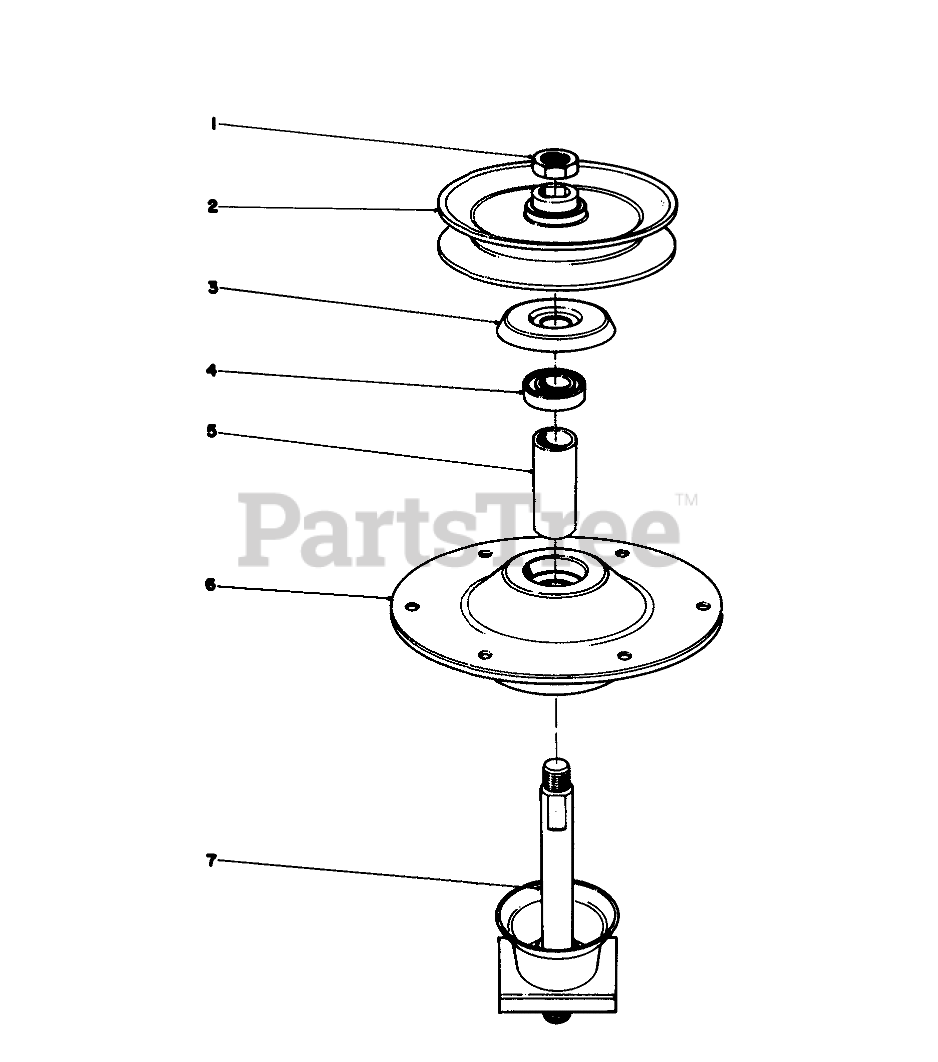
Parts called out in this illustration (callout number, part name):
1	Locknut
2	PULLEY B
3	COVER-DUST
4	BEARING
5	SPACER
6	Housing
7	SHAFT & SADDLE ASM
